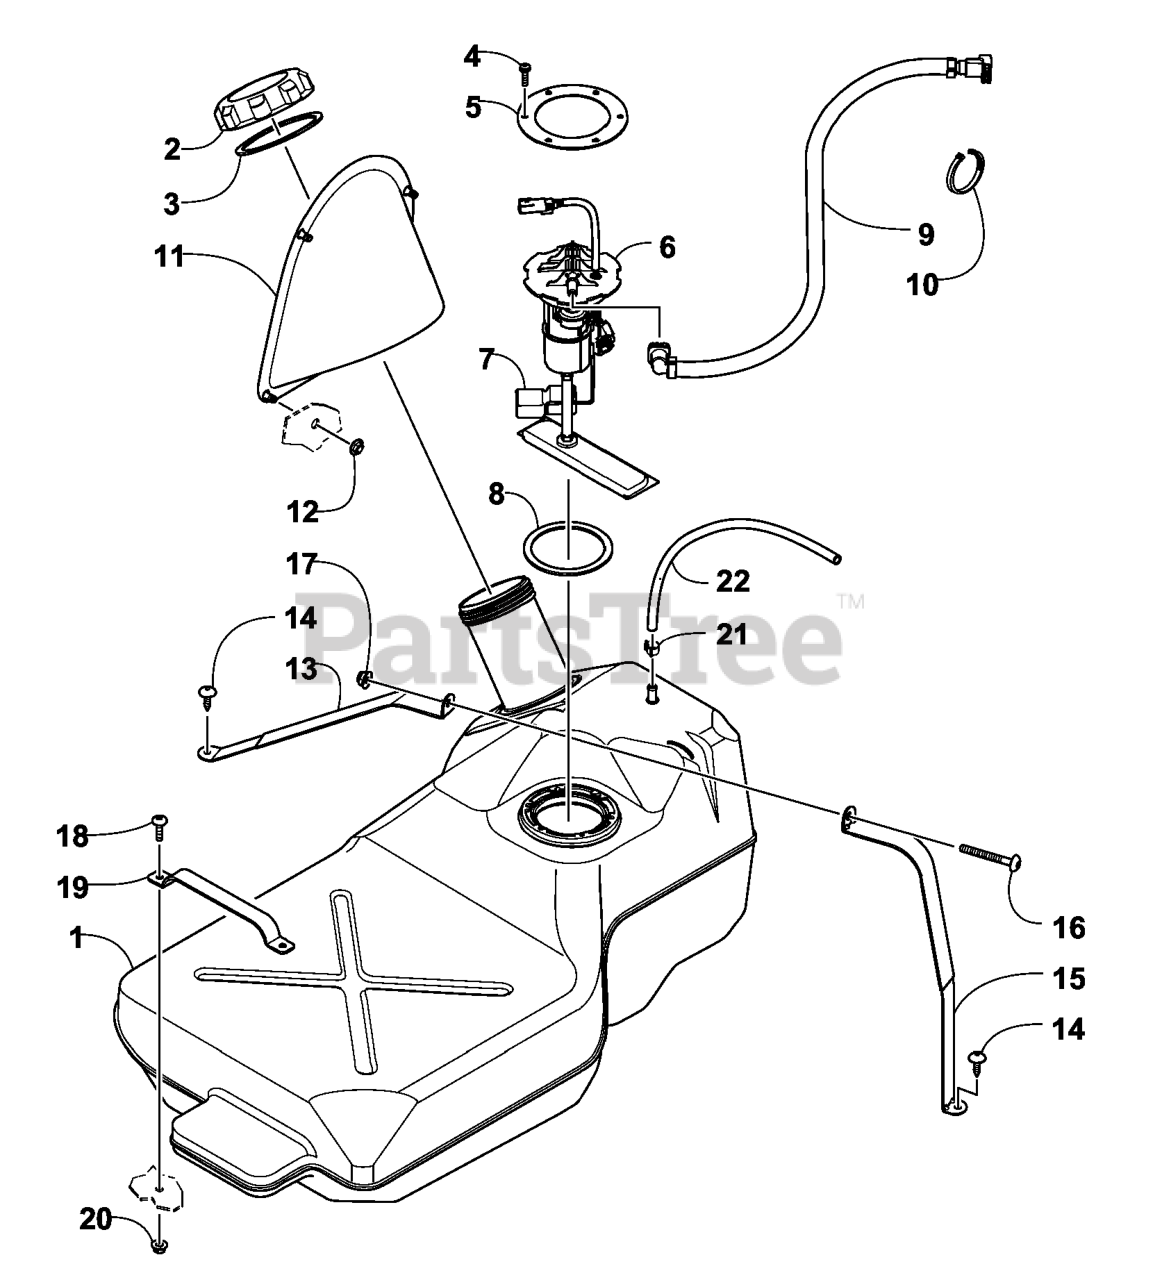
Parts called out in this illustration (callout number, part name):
1	FUEL TANK ASM
2	CAP-FUEL
3	SEALCAP, GAS
4	SCREW-TSPH, TF
5	MOUNT-PUMP, FUEL
7	FLOAT-FUEL PUMP
9	Hose, Gasline
10	TIE-CABLE
11	INSERT-FUEL CAP
12	NUT-STAMPED
14	SCREW-TSTRH, SELFTAP
15	STRAP-FUEL TANK
16	JACKSHAFT
17	LINKAGE,LOWER CALIPER RH
18	SCREW-TSPRH
19	BRACKET-MOUNT, FUEL TANK
20	NUT-HH, SEMS
21	CLAMP-SNAP
22	HOSE-FUEL
